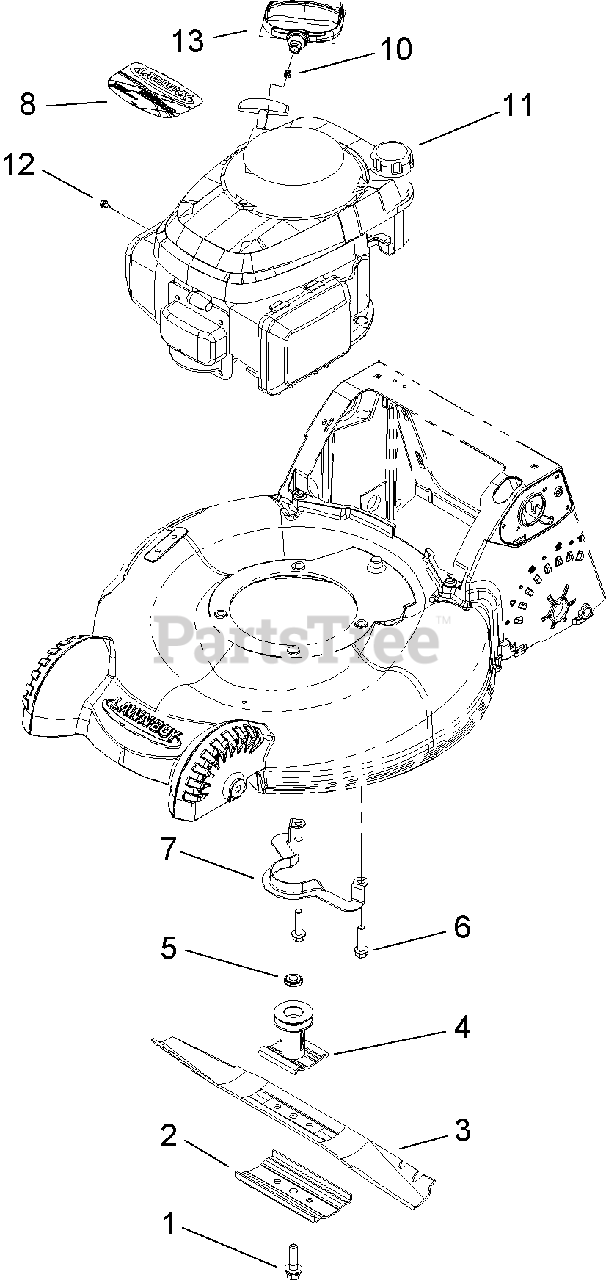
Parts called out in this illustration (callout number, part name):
1	BOLT-BLADE
2	SUPPORT-BLADE
3	BLADE-21 INCH
4	BLADE DRIVER ASM
5	Spacer-Driver
6	SCREW-HWH
8	DECAL-ENGINE
10	STOP-ROPE
12	SCREW-HWH
13	HANDLE-RECOIL
